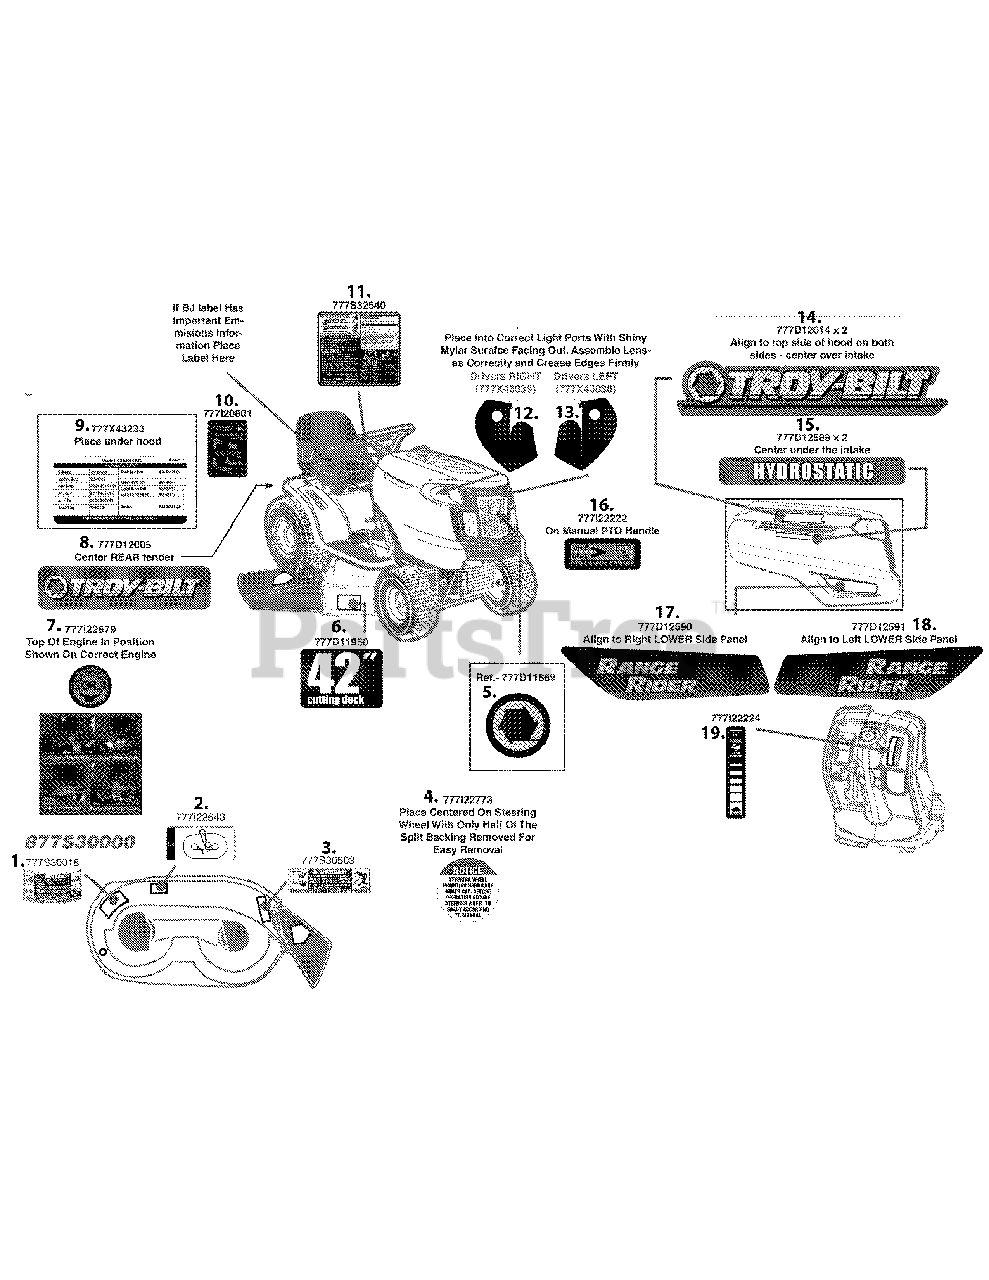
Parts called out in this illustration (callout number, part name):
1	LABEL-DECK SAFETY
2	LABEL-DECK BELT ROUTE 42"
3	LABEL-DANGER CHUTE
4	LABEL-RIDER:SECURE WHEEL
5	LABEL-EMBOSSED TROYBILT
6	LABEL-RIDER DECK TROY 42"
7	LABEL-CHECK ENG OIL
8	LABEL-RIDER REAR FENDER TROY
9	LABEL:RIDER:PARTSLIST
10	LABEL-HITCHPLATE
11	LABEL:RIDER SAFETY HYD W/CRSE
12	LABEL-RIDER K STYLE RH
13	LABEL-RIDER K STYLE LH
14	LABEL-RIDER HOOD K STYLE TROY
15	LABEL:RIDER:KSTYHOOD:HYDRO
16	LABEL-PTO HANDLE
17	LABEL:RIDER:RTLOWHDSD
18	LABEL:RIDER:LFTLOWHDSD
19	LABEL-DASH RH
